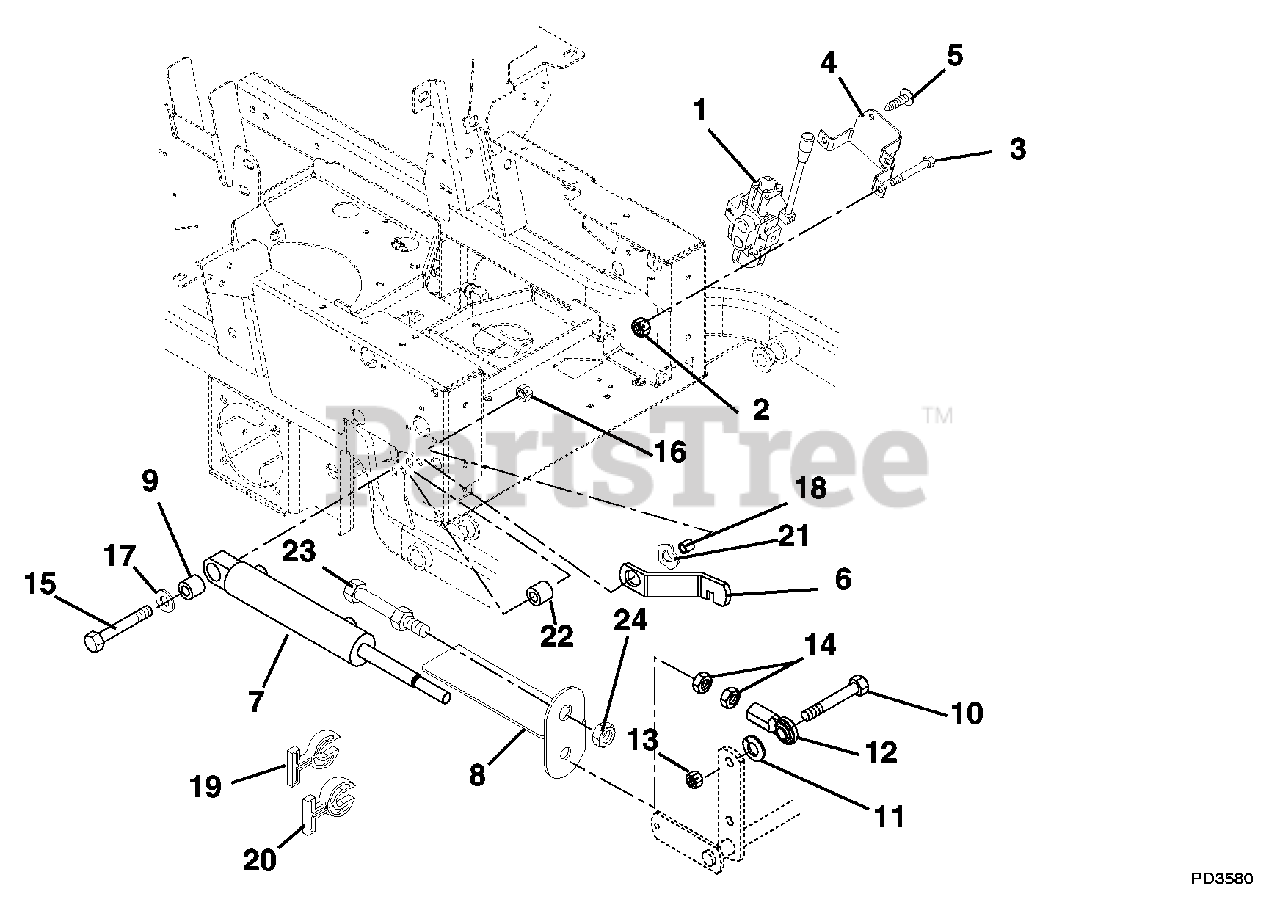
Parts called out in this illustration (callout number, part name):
1	Valve, Hydraulic
2	Nut, Locking Top Flange .31-18
3	Bolt, Hex .31-18 x 2.25 Grade 5
4	Valve Mounting Bracket
5	Screw, Tapping .38-16 x .50 Hex Washer Head
7	Cylinder, Hydraulic Lift
8	Strap, Cut Indicator/Guard
9	Bushing .516 x 1.000 x 1.050
10	Bolt, Hex .62-11 x 2.25 Grade 8
11	Washer, Lock .62 x .156
12	Rod End - Female - Right Hand .63
13	Nut, Locking Center .62-11
14	Nut, Jam .625-18
15	Bolt, Hex .50-13 x 3.50 Grade 5
16	Nut, Locking Top Flange .50-13
17	Washer, Flat Steel .515 x 1.625 x .25
18	Bushing, Flange .515 x .75 x .275 x 1.12
19	Stop, Cylinder .34 Thick
20	Stop, Cylinder .68 Thick
21	Washer, Wave .076 x 1.12 xz .08
22	Spacer .50 I.D. x .88 O.D. x .88
24	Nut, Jam Center Lock .75-16
